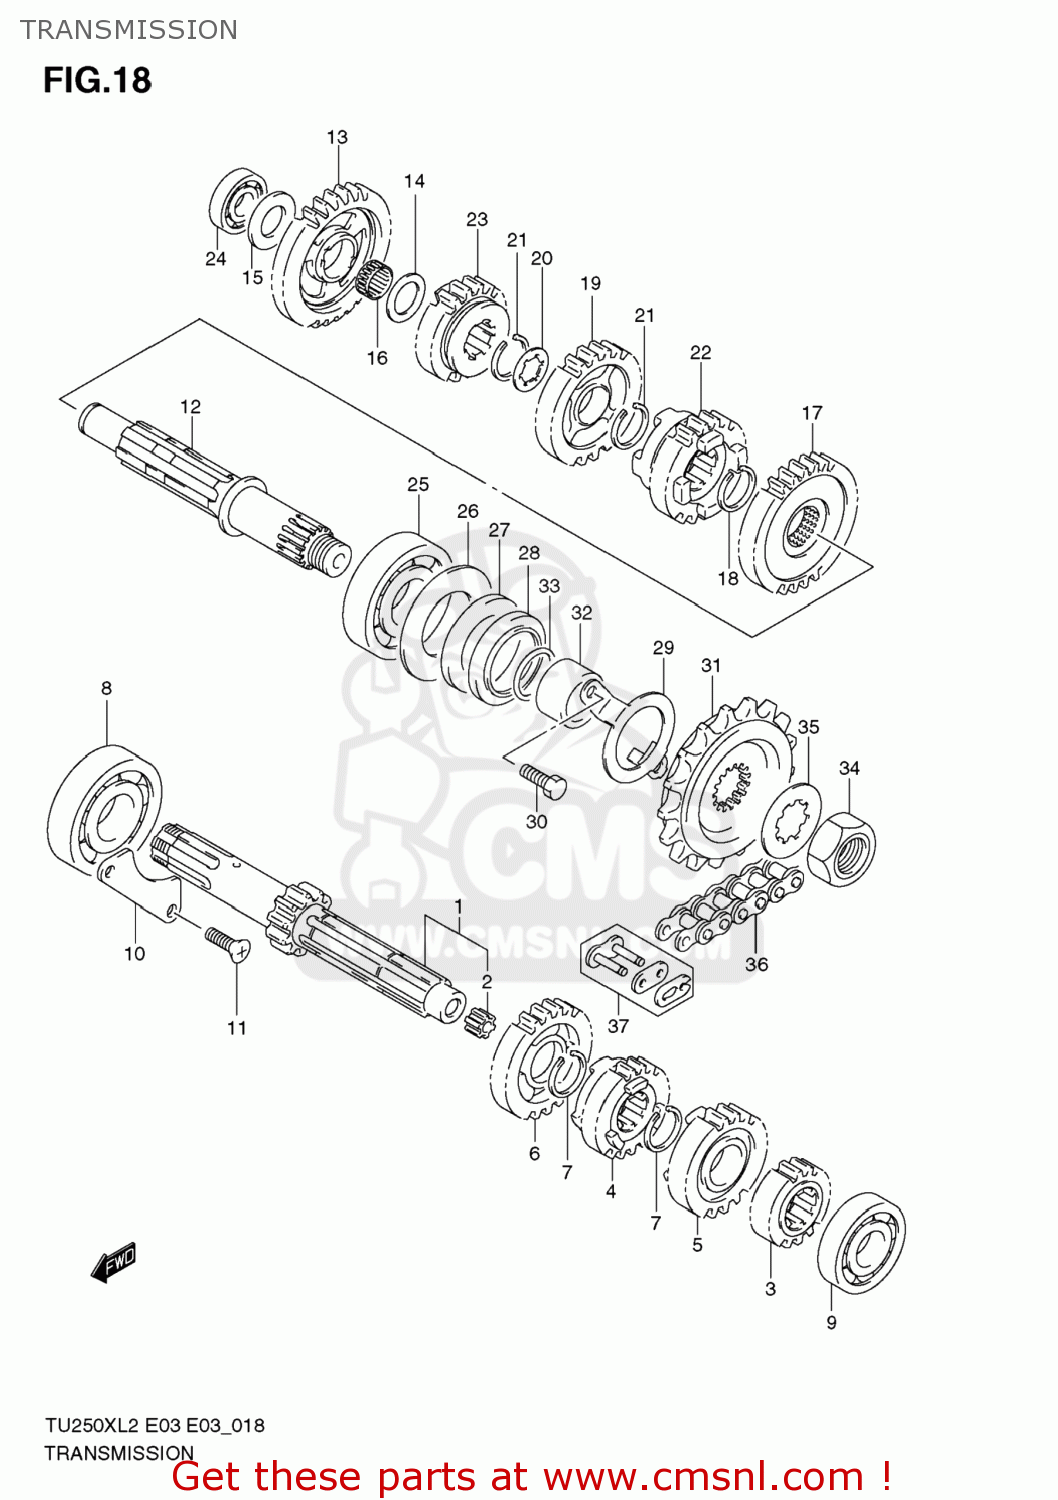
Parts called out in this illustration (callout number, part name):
1	SHAFT,COUNTER(NT:11)
2	BUSH
3	GEAR,2ND DRIVE(NT:16)
4	GEAR,3RD DRIVE(NT:20)
5	GEAR,4TH DRIVE(NT:21)
6	GEAR,5TH DRIVE(NT:22)
7	CIRCLIP
8	BEARING(22X56X16)
9	BEARING(17X40X12)
10	RETAINER,CNTR SHAFT BEARING
11	SCREW(6X12)
12	SHAFT,DRIVE
13	GEAR,1ST DRIVEN(NT:29)
14	SHIM(17X28X1)
15	WASHER
16	BEARING(17X21X9.8)
17	GEAR,2ND DRIVEN(NT:27)
18	CIRCLIP
19	GEAR,3RD DRIVEN(NT:24)
20	WASHER,LOCK
21	CIRCLIP
22	GEAR,4TH DRIVEN(NT:20)
23	GEAR,5TH DRIVEN(NT:18)
24	BEARING
25	BEARING(22X56X16)
26	WASHER(35X55X1)
27	SEAL,OIL(30X43X5)
28	SEAL,OIL(30X43X7)
29	RETAINER,DRIVE SHAFT OIL SEAL
30	BOLT
31	SPROCKET,ENGINE(NT:15)
32	SPACER
33	O RING(D:2.5,ID:21)
34	NUT
35	WASHER,LOCK
36	CHAIN(DID520VC5,108LE)
37	JOINT SET,CHAIN
